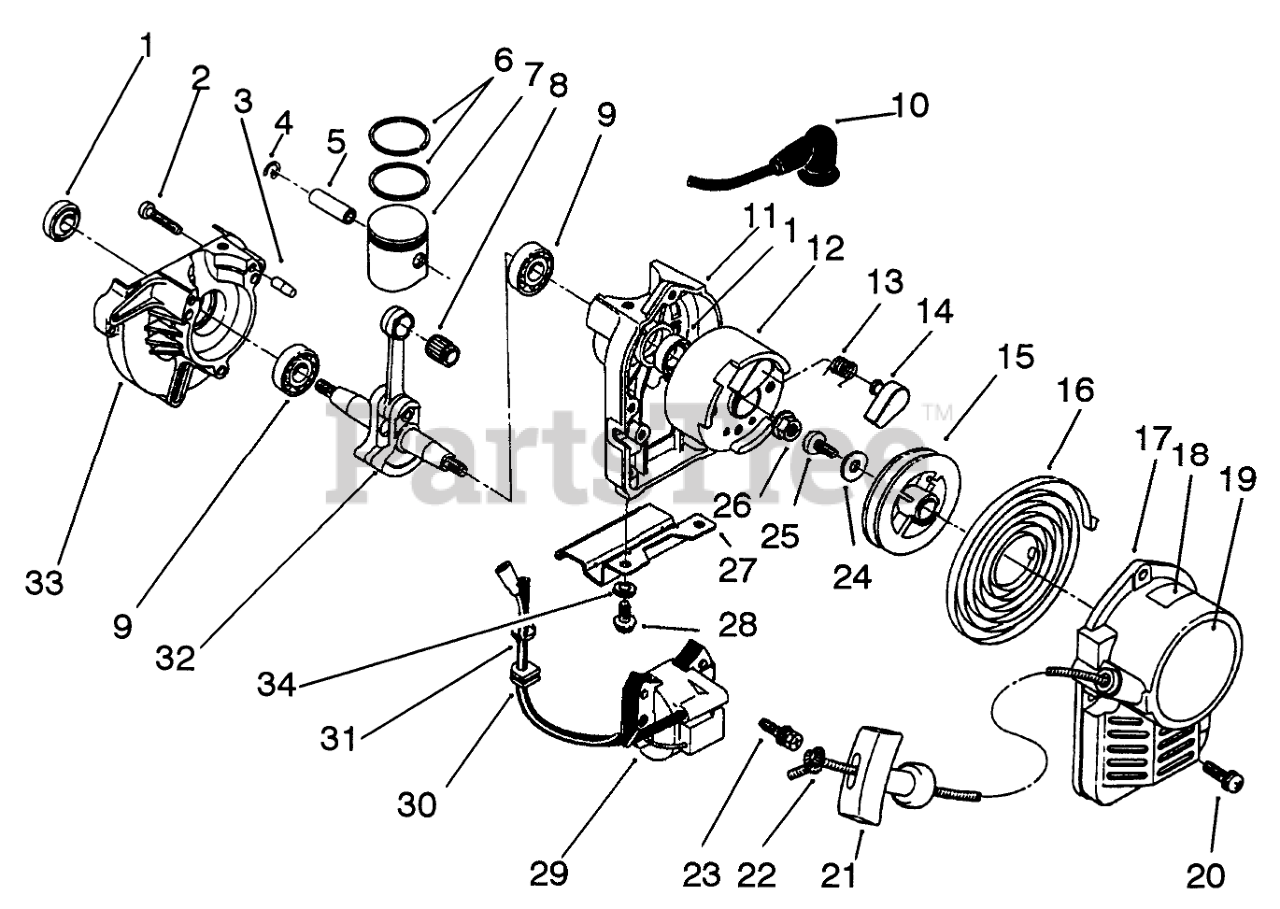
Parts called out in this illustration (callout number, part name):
1	OIL SEAL
2	Screw
4	PISTON PIN CLIP
5	PISTON PIN
6	SEAT VALVE
7	Piston Assembly (Incl. Ref. #5)
8	NEEDLE BEARING
9	BEARING
10	CAP-PLUG
11	STARTER CASE
12	Rotor Assembly (Incl. Ref. #13-14)
13	RETURN SPRING
14	RATCHET
16	SPRING
17	STARTER CASE
18	DECAL-SURFACE, HOT
19	Decal-Toro
20	SCREW & WASHER
21	Knob-Starter
22	Rope-Recoil
23	BOLT & WASHER
24	Washer
25	SCREW
27	STAND SUPPORT
28	M6 X 1 X 1/2 MWH SCREW
29	IGNITION COIL
30	GROMMET
32	CRANKSHAFT ASSEMBLY
33	DRIVE CASE
34	WASHER-LOCK
